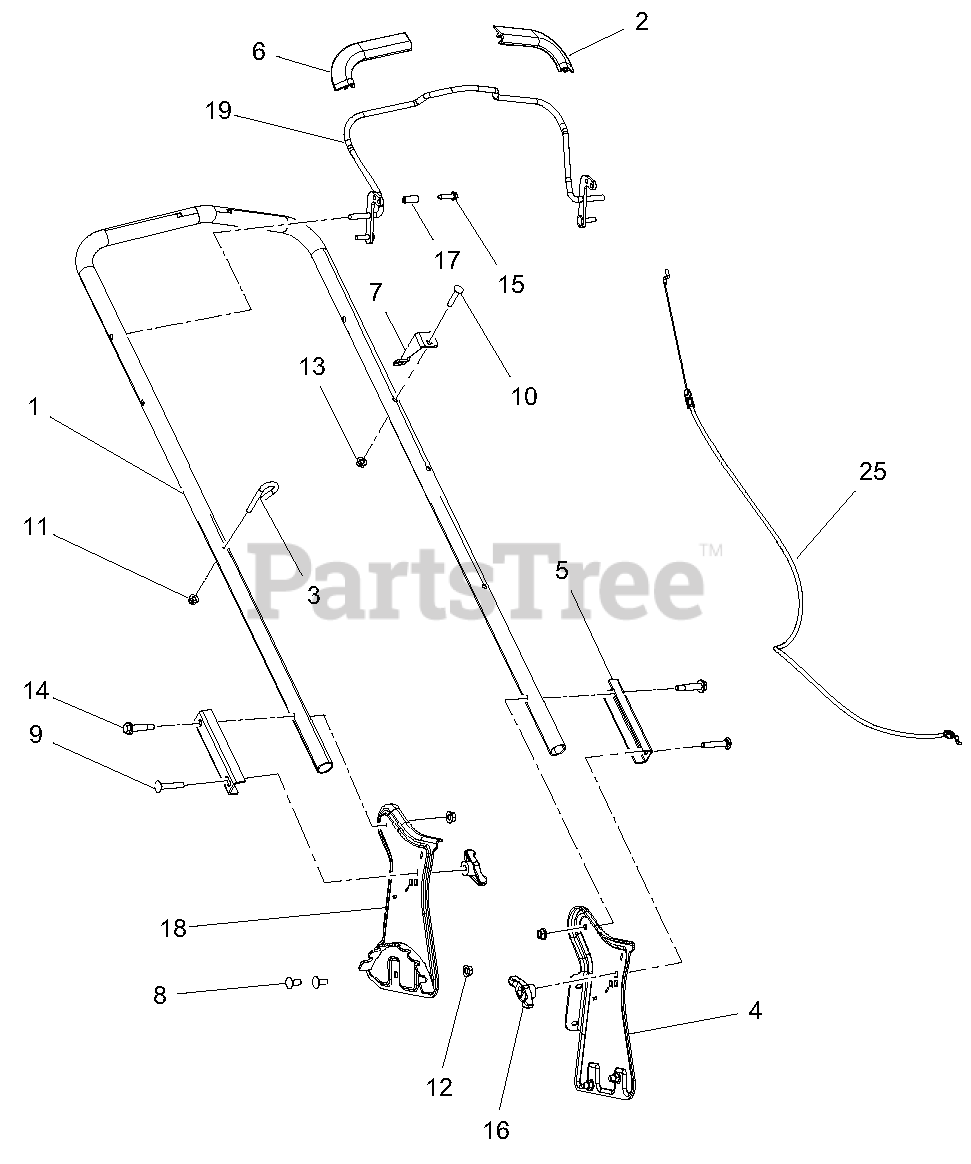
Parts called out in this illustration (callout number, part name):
1	HANDLEBAR
2	GUARD, FINGER - LH
3	GUIDE, RECOIL ROPE
4	SUPPORT, LH HANDLEBAR
5	BRKT, HANDLEBAR FIXED ADJUST
6	HAND GRIP WITH DECAL
7	BRKT, CABLE ANCHOR - LM PUSH
8	@BLT-RDHDSQNK .31-18X.75 G5 YWZC
9	@BLT-RDHDSQNK .31-18X1.75 G5 YWZC
10	@BLT-RDHDSQNK .25-20X1.50 G5
11	NUT-LK-NYL-FLG .25-20 YWZC
12	@NUT, LK-TOP-FLG .312-18 YWZC
13	@NUT, LK-TOP-FLG .25-20 YWZC
14	BLT, SHLDR .50X1.30X.38-16 GR5
15	SCR-TAP .25-20X1.00 HWH TR YZ
16	KNOB, WING .31-18 UNC NYL/TALC
17	CAP, VINYL
18	WLDMT, RH SIDE PLATE-ARIENS
19	BAIL, OPC
25	CABLE, OPC
